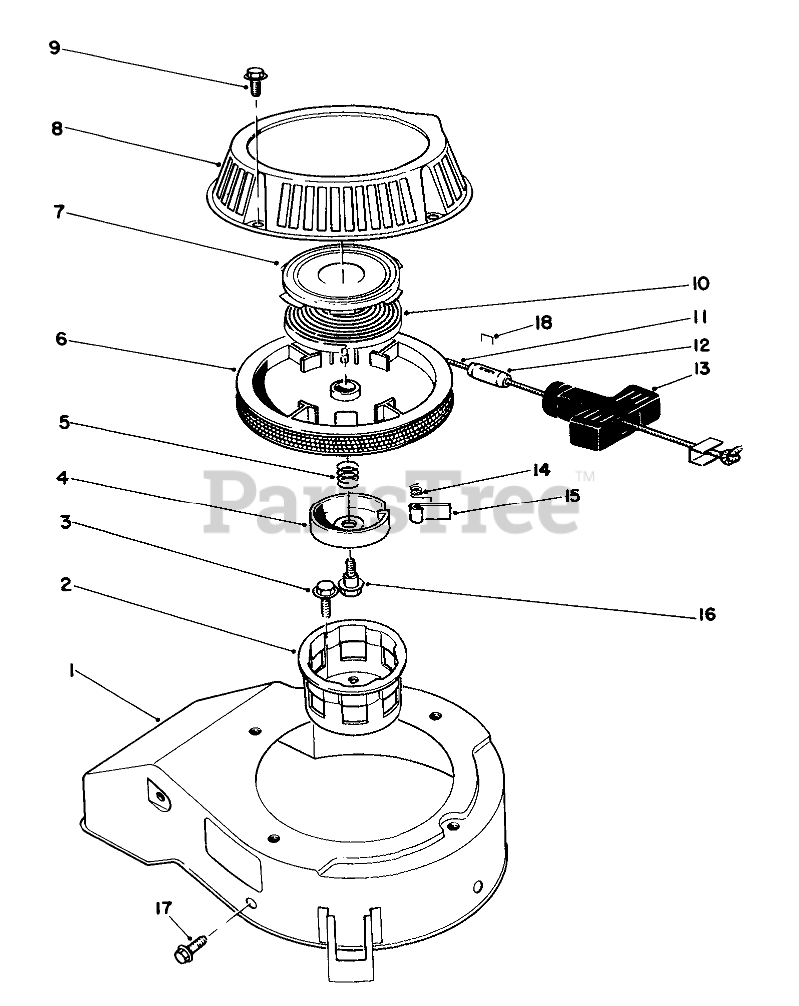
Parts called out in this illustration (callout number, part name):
1	COVER
2	CUP - STARTER
4	RETAINER
5	SPRING
7	Retainer Cup-Recoil Spring
9	SCREW-HHF
10	Spring-Recoil
11	ROPE-STARTER
13	HANDLE-RECOIL
14	SPRING
18	Staple
